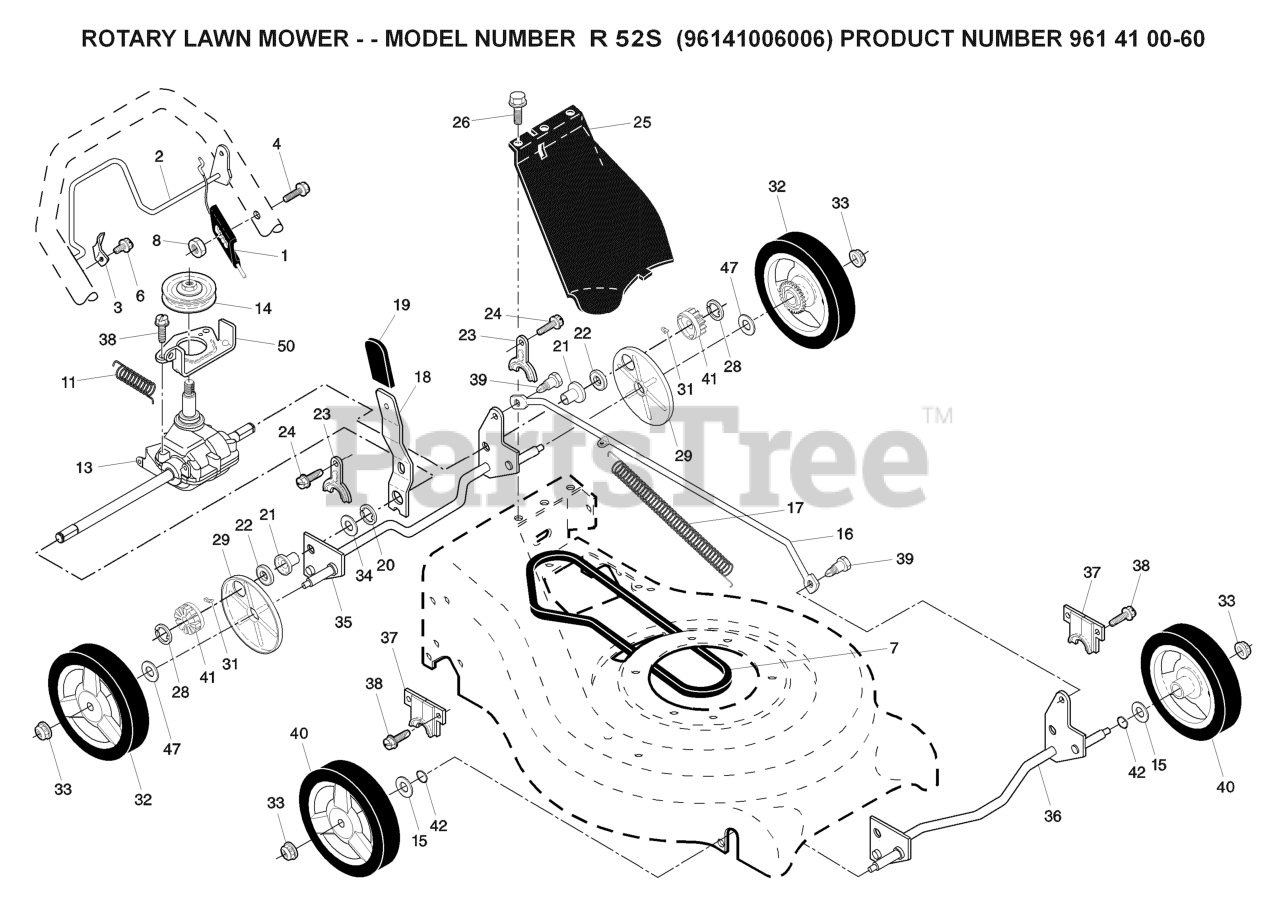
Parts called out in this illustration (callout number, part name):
3	DOWNSTOP BRACKET
7	RP.BELT.DRIVE.RGD.SS.WALK
8	NUT.HEX.FLANGE.1/4
13	TRANSMISSION.21.RWGD
14	PULLEY.RGD.SS.3.25OP
15	WASHER.FLAT.1/2
16	ROD.CONNECTING.SPT.BLACK
17	SPRING EXTENSION
18	SPRING.SELECTOR.
19	KNOB.EXT.ERGO.BLACK
21	BEARING SUPPORT
22	BEARING
23	BRACKET
24	SCREW 14-20 X 5/8
25	COVER.DRIVE.21.RWGD.MO
28	E-RING 7/16 RE
29	COVER.DUST.WHEEL
31	PAWL, DRIVE
32	WHEEL & TIRE ASSY, REAR
33	NUT.HEX.FLANGE.3/8-16.LO(3 2)
35	SHAFT ASSY REAR
36	SHAFT ASSY, FRONT
37	RETAINER.FRONT.SHAFT
39	SHOULDER BOLT SEMI GIMLET PT.
40	WHEEL & TIRES ASSY, FRONT
41	PINIION.14.TOOTH.RGD
42	O-RING..070X.487.NEOPRENE
47	WASHER FLUT
50	BRACKET.BELT.KEEPE/AUT*SUBS/2*
